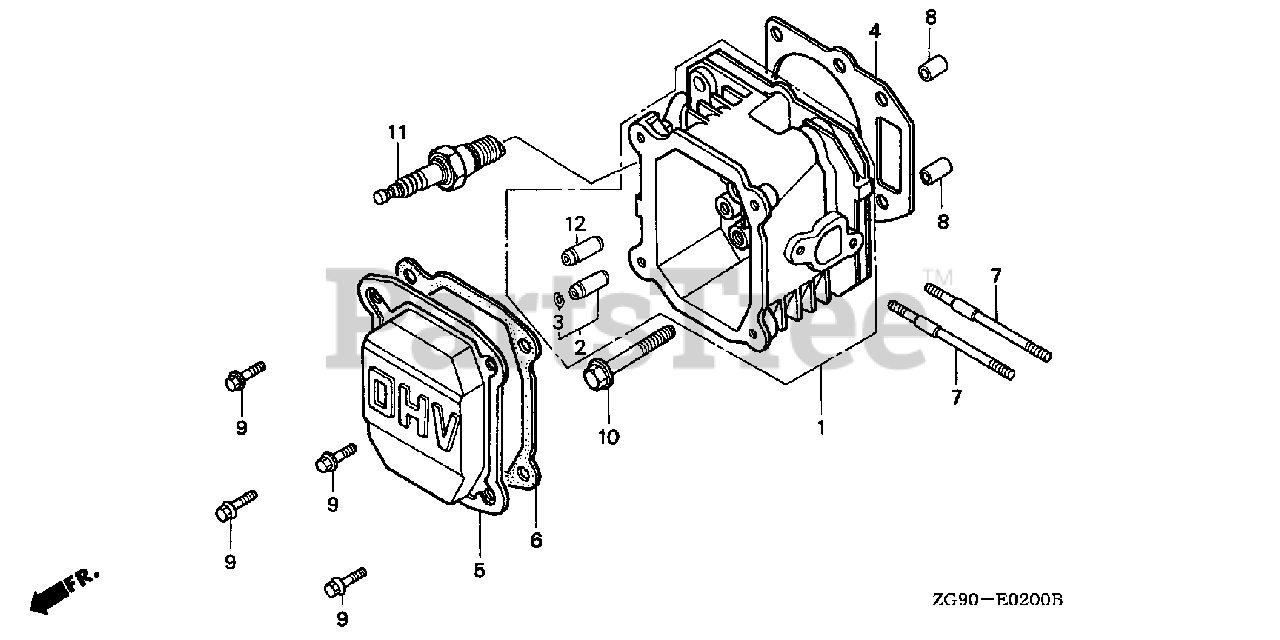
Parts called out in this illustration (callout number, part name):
1	CYLINDER HEAD (USA)
2	GUIDE, EX. VALVE (OVER SIZE)
3	CLIP, VALVE GUIDE
4	GASKET, CYLINDER HEAD
5	COVER, HEAD
6	GASKET, HEAD COVER
8	PIN, DOWEL (10X16)
9	BOLT, FLANGE (6X14)
10	BOLT, FLANGE (8X50)
11	SPARK PLUG (BPR4ES) (NGK)
11	SPARK PLUG (BPR5ES) (NGK)
11	SPARK PLUG (BPR6ES) (NGK)
12	GUIDE, VALVE (OVER SIZE) Use from Engine SN 6324986.
